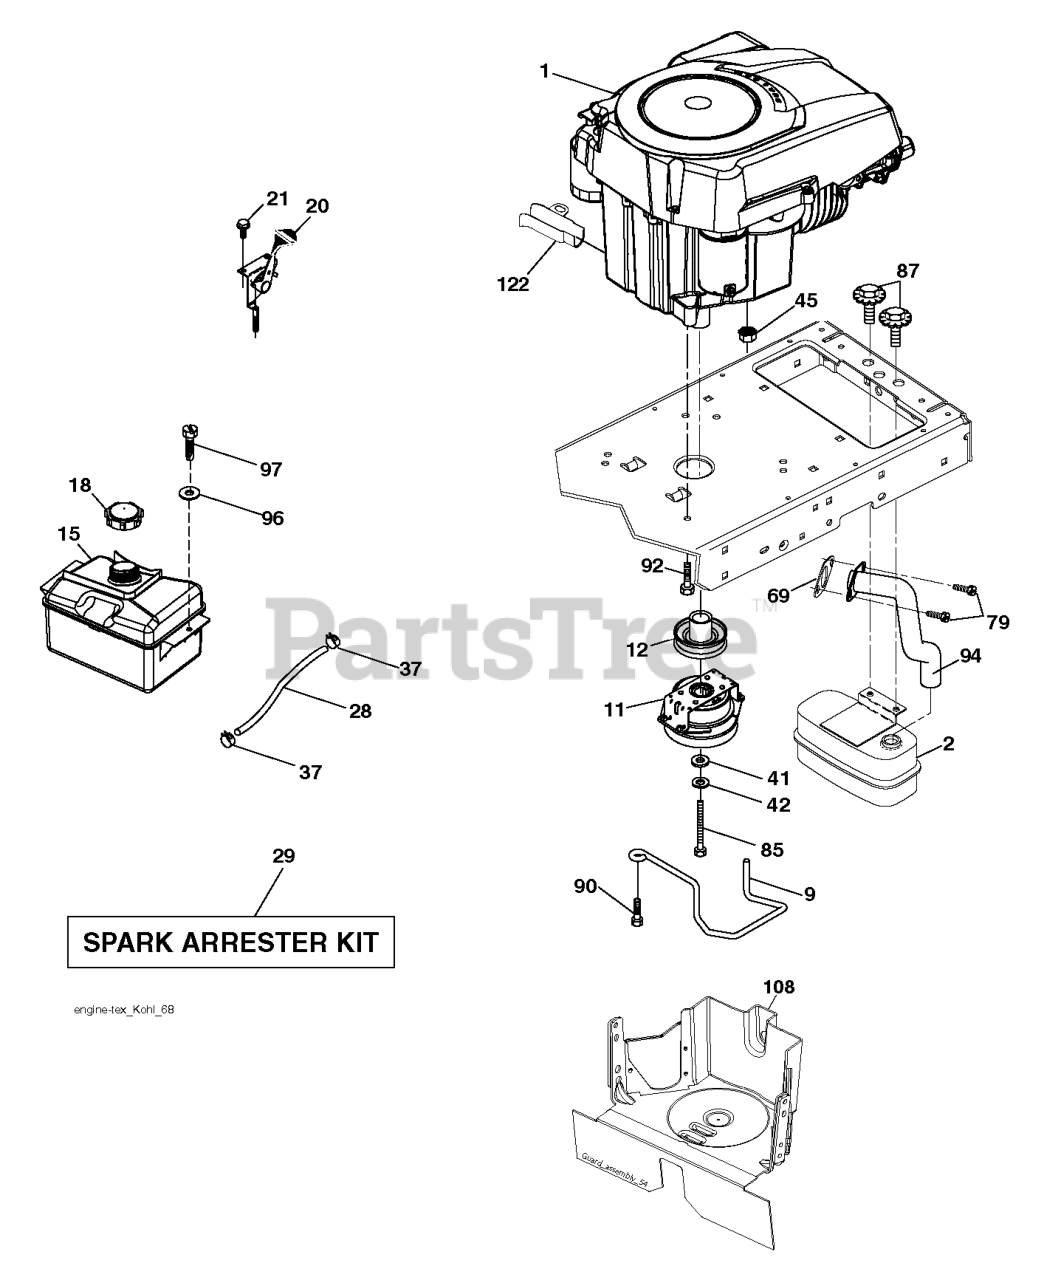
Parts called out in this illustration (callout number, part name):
2	MUFFLER.SINGLE.LRG.BRIGGS.KOHL
9	KEEPER BELT ENGINE
11	CLUTCH.ELECTRIC.LT.48"*
12	PULLEY.ENGINE.TUFFTORQ
15	FUEL.TANK.ASM.NON-EPA
18	CAP ASM.FUEL.2.25"FR.
20	CONTROL.TH/CK.C.
21	SCREW.#10 X 0.750.BOS
28	LINE.FUEL.20
29	KIT.SPARK ARRESTOR 794945 B&S
37	HOSE CLAMP
42	LOCKWASHER
45	NUT
69	GASKET.EXHAUST.KOHLER
79	SCREW.SOCKET HD.5/16-1
85	BOLT HEX 7/16-20X4-1/4"
87	BOLT.5/16-18UNCX3/4 W/SEMS.BLK
90	SCREW 3/8-16X1
92	SCREW 3/8-16X1
94	TUBE.EXHAUST.KOHLER.COURAGE
96	WASHER
97	SCREW HEXWSHR 1/4-20X3/4
108	COVER PULLEY
122	EXTENSION DRAIN OIL
